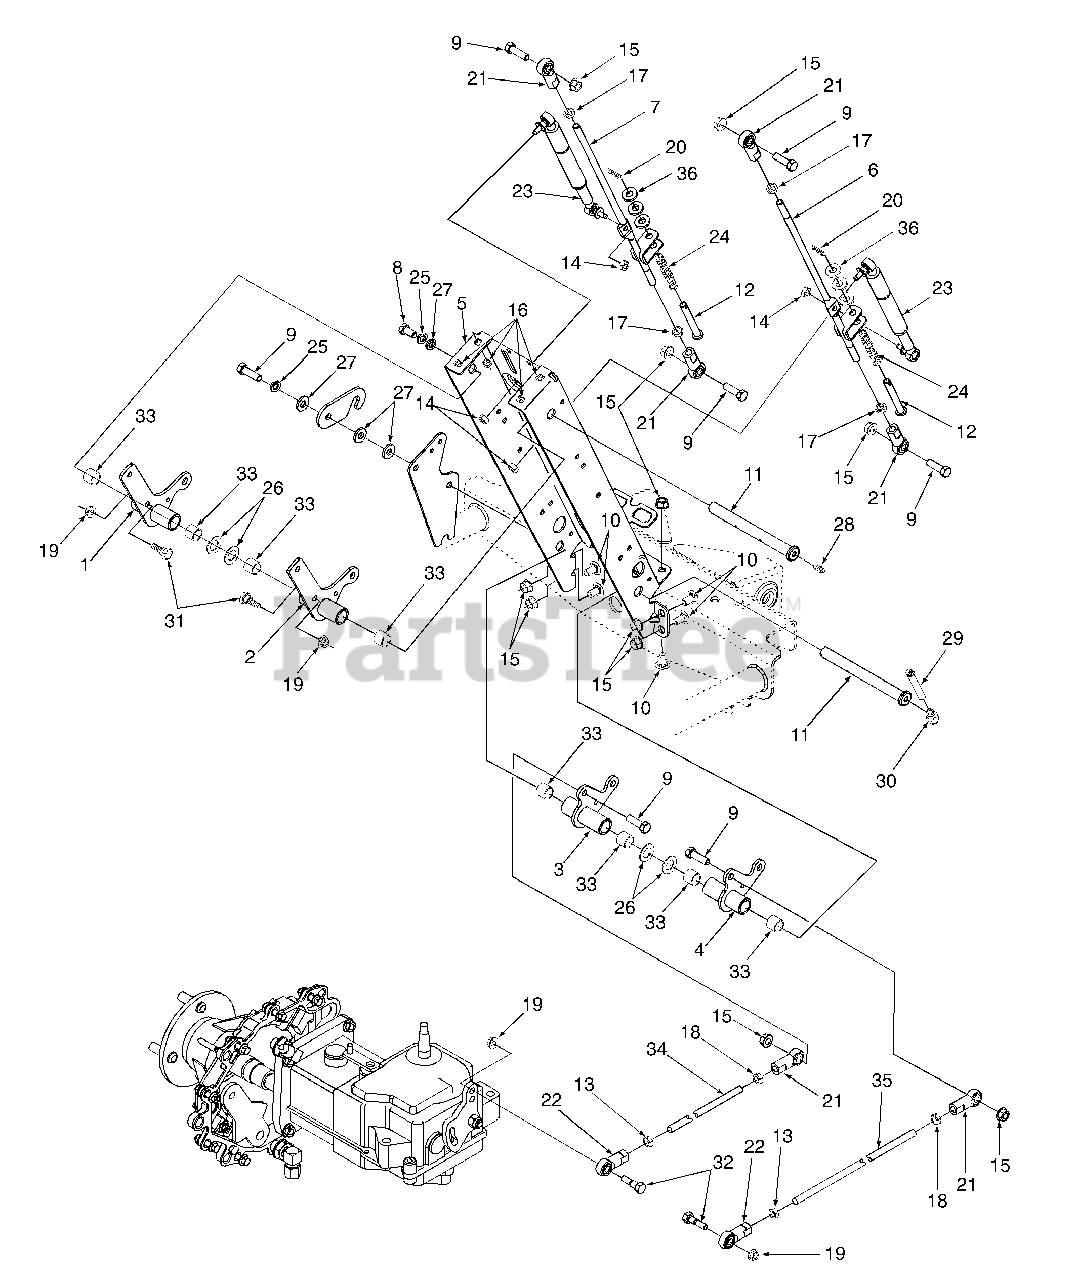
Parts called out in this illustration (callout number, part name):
6	Rod Ass'y, Control RH
7	Rod Ass'y, Control LH
8	Screw, Hex Cap 3/8-16 x 3/4 GR5
9	Screw, Hex Cap 3/8-16 x 1.25 GR5
10	Bolt, Carriage, 3/8-16 x .75
11	Shaft, Control
12	Pin, .374 Dia. x 2.88 Lg.
13	Nut, Hex Jam LH Thrd, 3/8-24
14	Nut, Hex Center Lock, M8 GR8.8
15	Nut, Hex Flange Lock, 3/8-16
16	Nut, Retainer, 1/4-20
17	Nut, Hex Jam, 3/8-24
18	Nut, Hex Jam, 3/8-24
19	Nut, Hex Flange Lock, 5/16-18 GR5
20	Pin, Internal Cotter
21	Rod End, Spherical RH, 3/8-24
22	Rod End, Spherical LH, 3/8-24
23	Cylinder, Damper
24	Spring, Compression
25	Washer, Lock, 3/8
26	Washer, Thrust, .625 x 1.12 x .06
27	Washer, Flat, .406 x .875 x .105
28	Fitting, Grease
29	Fitting, Grease w/Tube
30	Adapter, 90° 1/4-20 Thrd.
31	Bolt, Shoulder, .437 Dia. x .268
32	Bolt, Shoulder
33	Bearing, Sleeve, .628 x .75 x .625
34	Rod, Control, LH 31-5/8 Lg.
35	Rod, Control, RH 35-3/8 Lg.
36	Flat Washer .406 ID x .87 x .06
